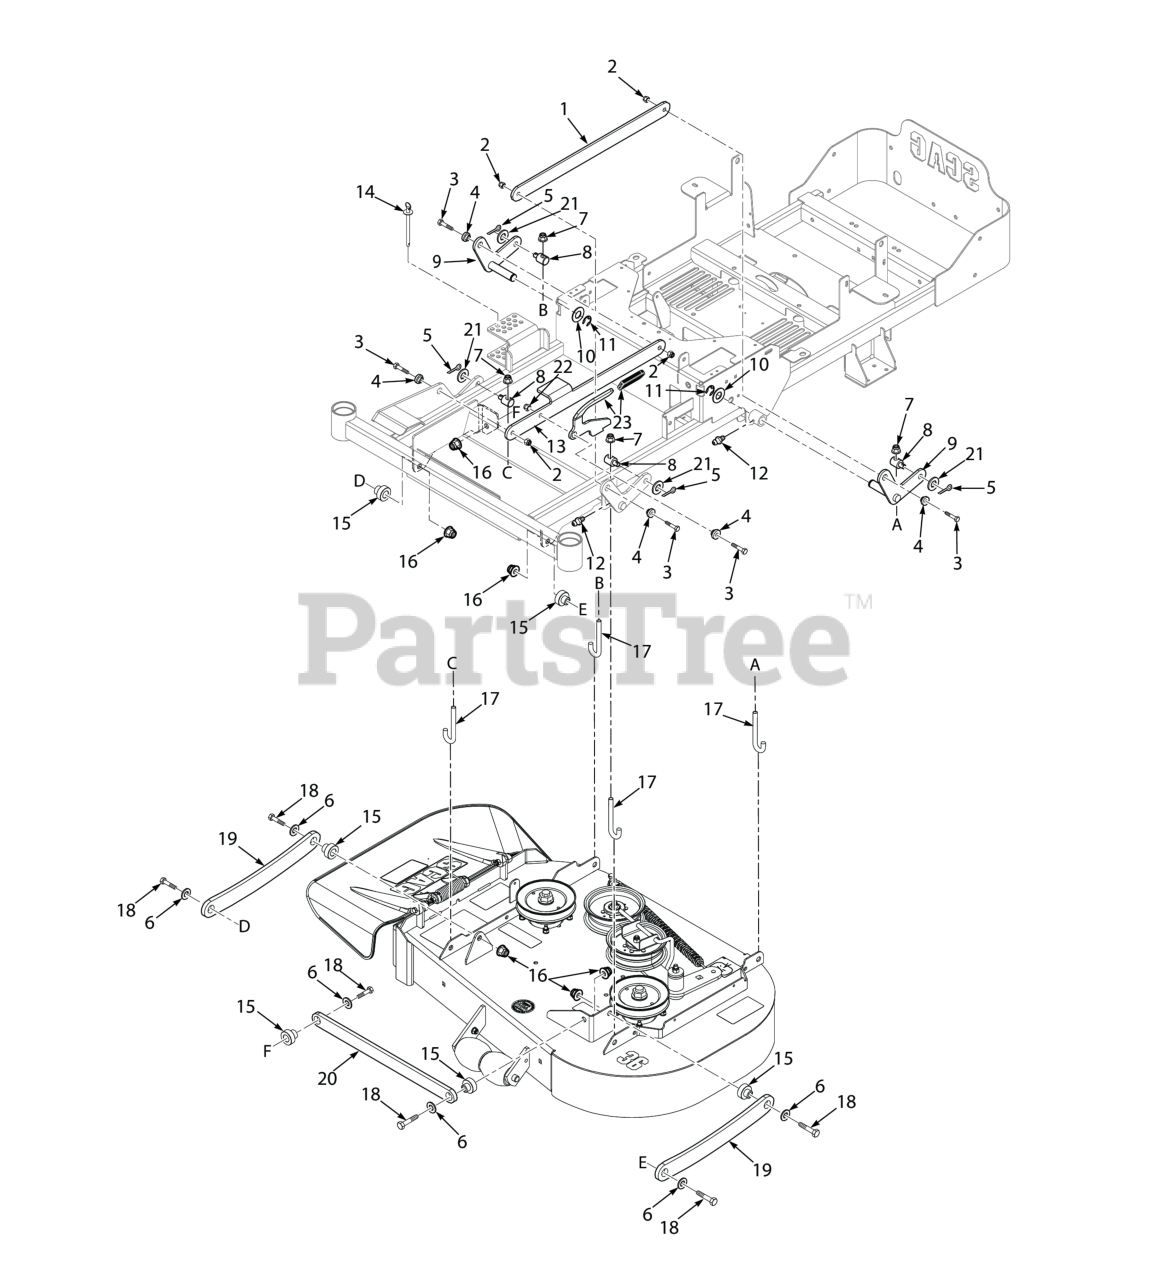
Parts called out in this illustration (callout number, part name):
1	Link, Deck Lift - LH
2	Nut, Flange Elastic Stop Nut, 3/8-16
3	Bolt, Hex Head 3/8-16 x 1-1/4", Kawasaki FX / FS
4	BUSHING, SPEED ADJUSTMENT LEVER
5	Pin, Cotter 3/16 x 1.0"
6	Flatwasher, 1/2 - .531 x 1.062 x .095
7	HEX LOCKNUT, ELASTIC STOP, 1/2-13
8	Joint, Swivel
9	Lift Bellcrank Weldment
10	Flatwasher, 3/4 (.766 x 1.250 x .060)
11	RETAINING RING, 3/4" EXTERNAL "E"
12	GREASE FITTING, STR. 1/4-28 SELF TAP.
13	Link, Deck Lift - RH
14	Pin Assembly, Deck Height
15	Bushing, Deck Lift
16	Nut, Elastic Stop 1/2-13, (STT-52 & STTII-52)
17	Rod, Deck Lift
18	Bolt, Hex Head 1/2-13 x 1-3/4"
19	Pull Arm, Deck
20	Lateral Link
21	Flatwasher, 5/8" (.656 x 1.312 x .095")
22	HEX NUT, ELASTIC STOP LOCK, 3/8-16
23	Lever Assembly (incl. Grip)
